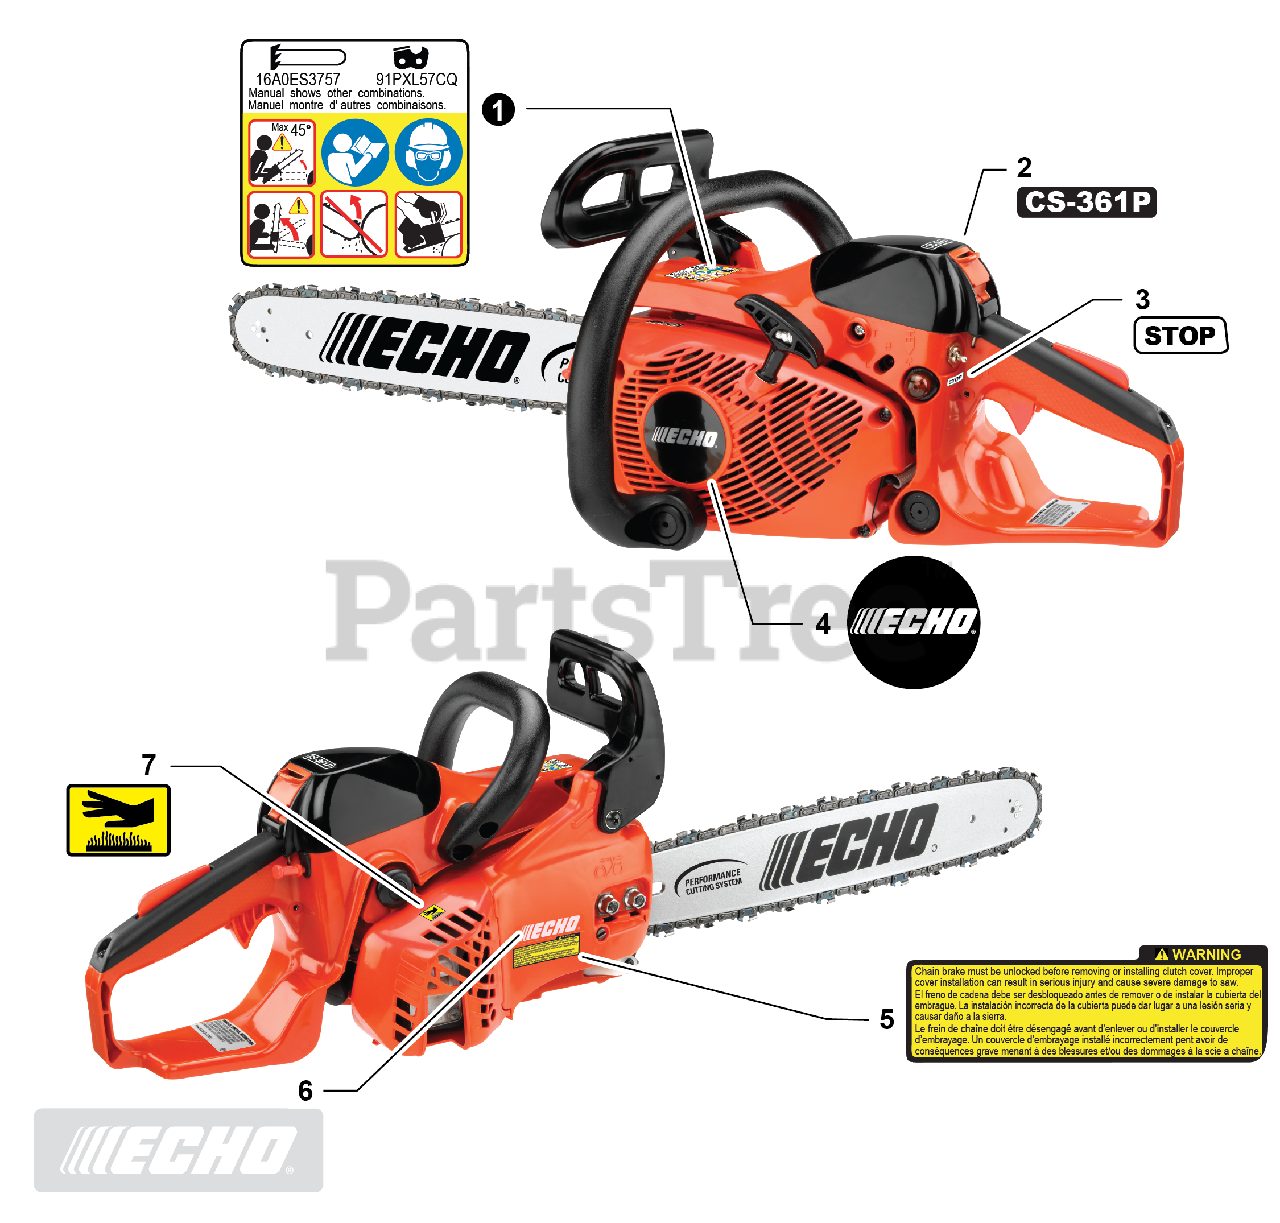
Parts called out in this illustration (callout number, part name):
1	LABEL, CAUTION
2	LABEL, MODEL CS-361P
3	LABEL, STOP
4	LABEL, ECHO
5	LABEL, WARNING
6	LABEL, ECHO
7	LABEL, CAUTION - HOT
